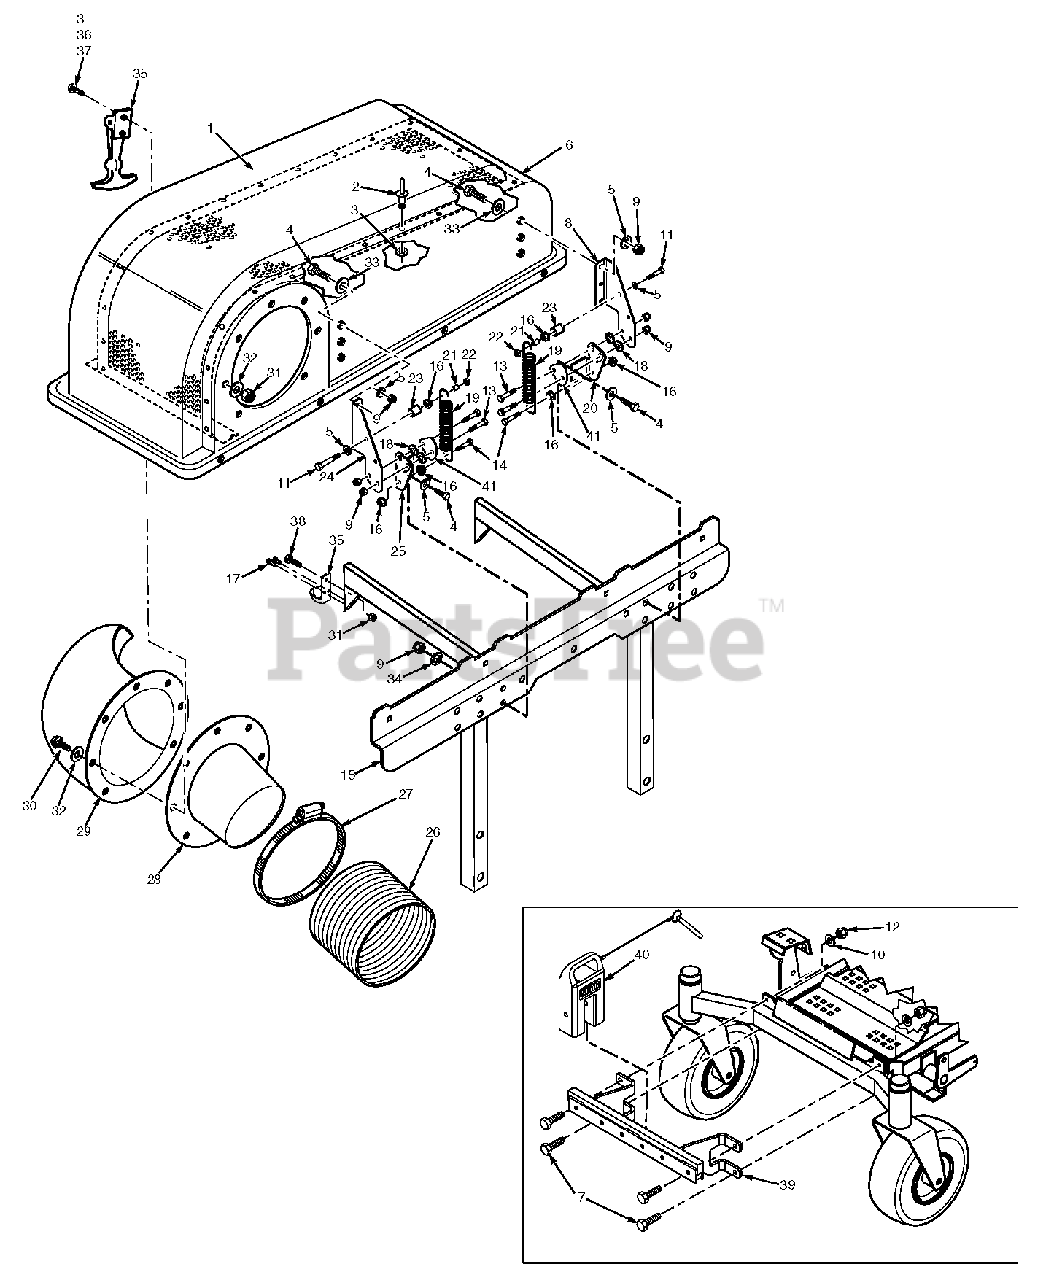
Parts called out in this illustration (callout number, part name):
1	Screen, Catcher Hood
2	Pop Rivet, 3/16 x .652
3	Flatwasher, 3/16-.196 x .469 x .048
4	Bolt, Hex Head 3/8-16 x 1-1/4"
5	Flatwasher, 3/8-.391 x .938 x .105
6	Hood Assembly, GC-STT
7	Bolt, Hex Head 7/16-14 x 1-3/4"
8	Hinge, Upper LH
9	Nut, Elastic Stop 3/8-16
10	Flatwasher, 7/16-.500 x 1-1/4"
11	Bolt, Hex Head 3/8-16 x 2-1/4"
12	Nut, Elastic Stop 7/16-14
13	Bolt, Hex Head 3/8-16 x 1-1/2"
14	Bolt, Hex Head 3/8-16 x 1-3/4"
15	Support Weldment, Bag Frame
16	Nut, Serrated Flange 3/8-16
17	Pop Rivet, 3/16 x .402
18	Bushing, Hopper Pivot
19	Spring, Hood Hinge
20	Hinge, Lower LH
21	Spacer
22	Locknut, 3/8-16
23	Spacer
24	Hinge, Upper RH
25	Hinge, Lower RH
26	Hose, 8" Dia. x 53"
27	Clamp, 8-5/8" Max Dia.
28	Tube, Filler
29	Elbow
30	Bolt, Hex Head 5/16-18 x 1-1/4"
31	Nut, Elastic Stop 5/16-18
32	Flatwasher, 5/16-.375 x .875 x .083
33	Flatwasher, 3/8- .406 x 1-1/2" x .179
34	Lockwasher, 3/8" Spring
35	Latch
36	Screw, #10-32 x 3/4"
37	Nut, Elastic Stop #10-32
38	Bolt, Hex Head 5/16-18 x 3/4"
39	Support Weldment, Weights
40	Weight Assembly
41	Guard, GC Hinge
